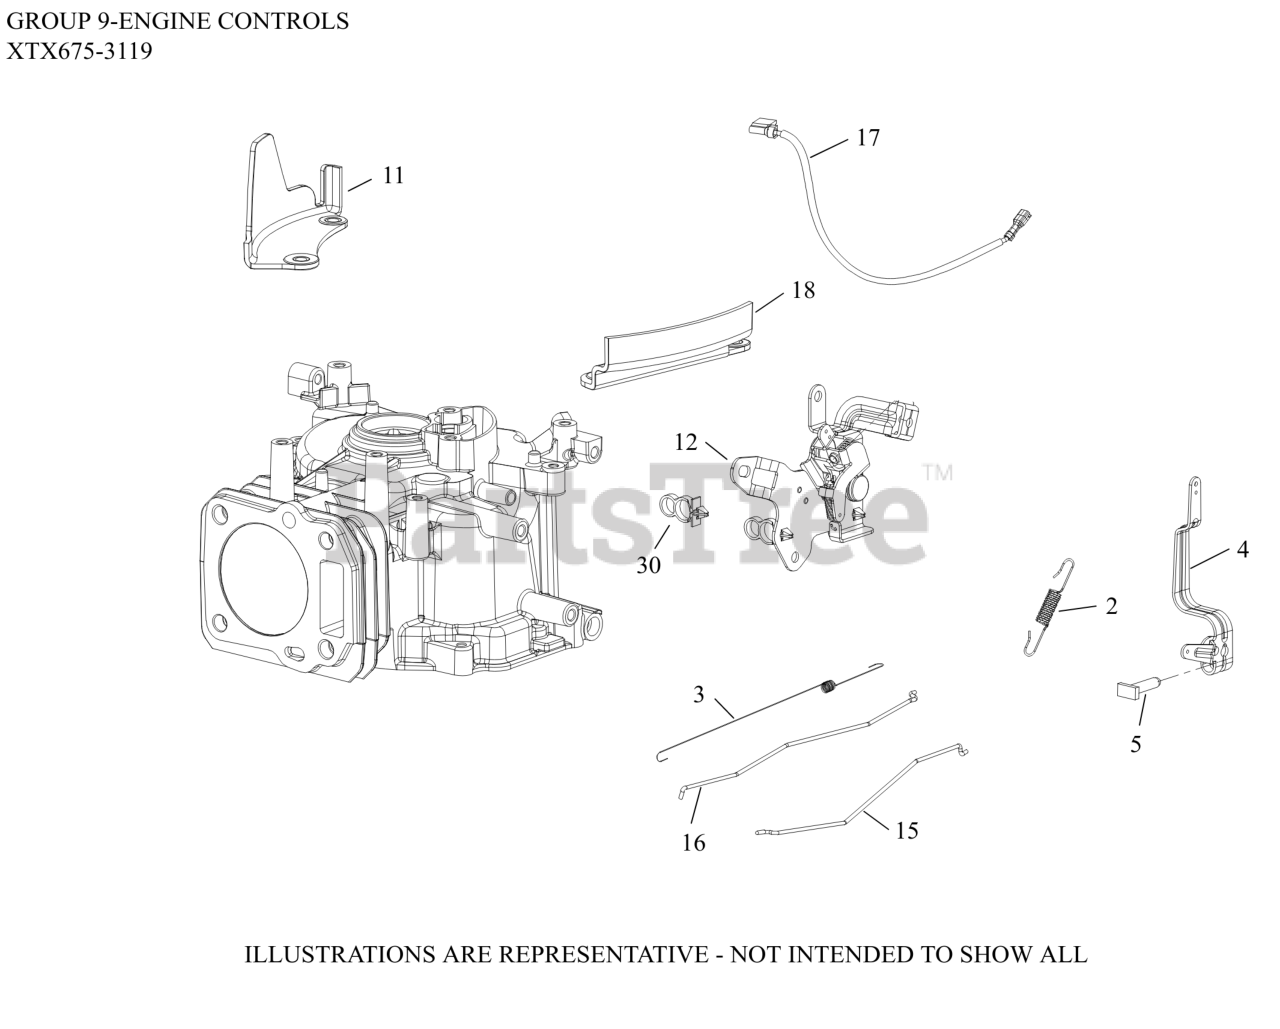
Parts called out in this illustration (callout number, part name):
2	SPRING, GOV (3301-3800 RPM)
3	SPRING, LINKAGE
5	SCREW, RECTANGLE HEAD (M6)
11	GUARD, FINGER
12	CONTROL ASSY, REMOTE VARIABLE SPEED
15	LINKAGE, CHOKE
16	LINKAGE, GOVERNOR
18	GUARD, FINGER
30	CLIP, FUEL LINE
34	LEVER, GOVERNOR
